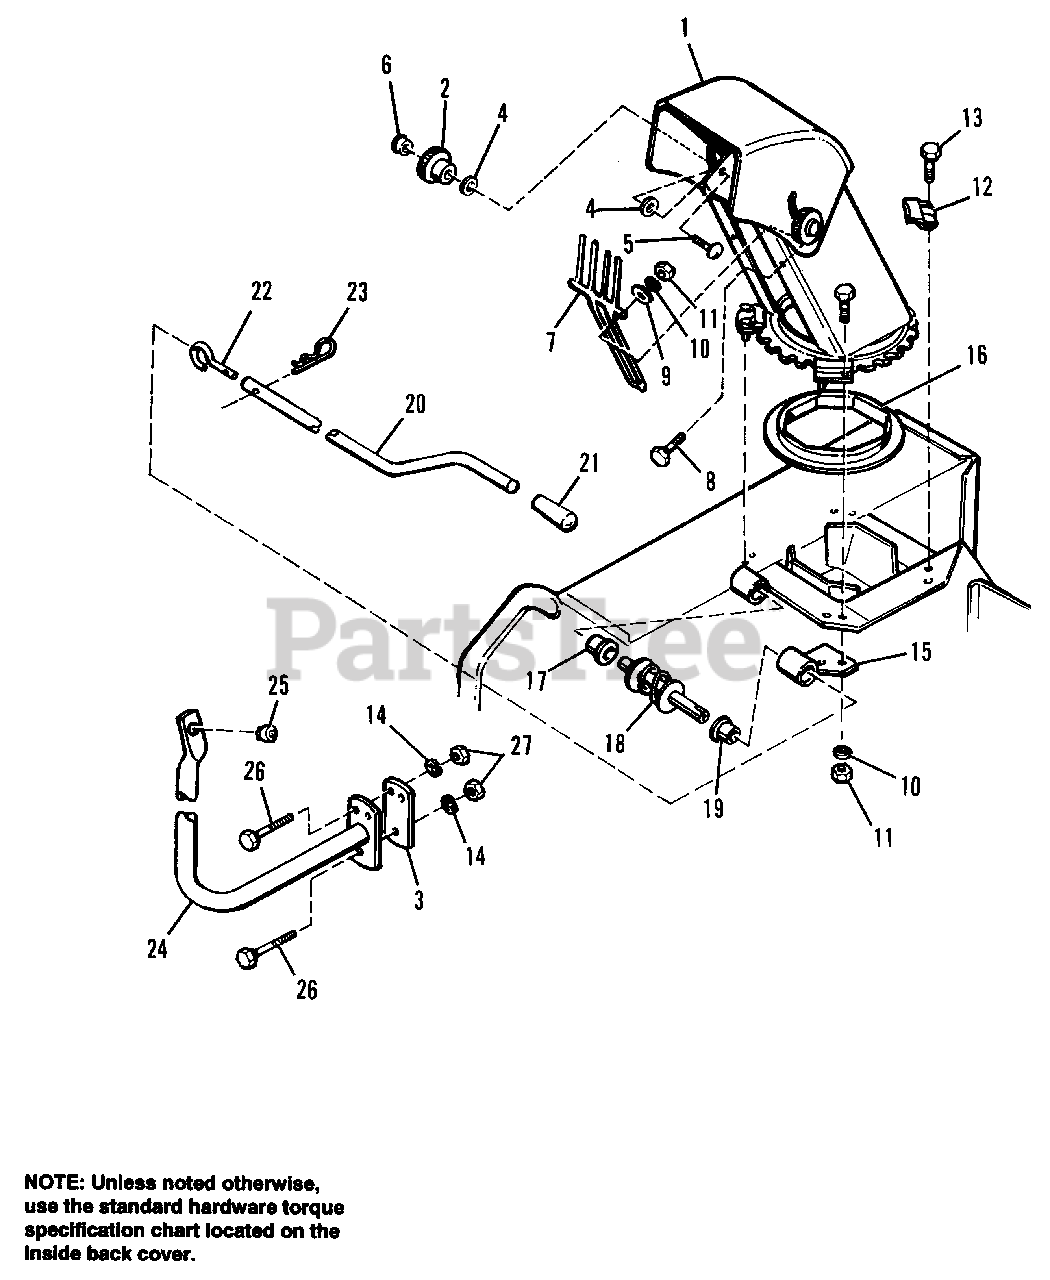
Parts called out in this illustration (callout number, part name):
1	CHUTE & DEFLECTOR ASSY.
3	SUPPORT, Fixation
4	WASHER, Nylon, 13/32 x 1 x 1/16
5	CARRIAGE BOLT, 5/16-18 x 1-1/2
6	NUT, Hex, Lock Esna, 5/16-18
8	CAPSCREW, Hex Hd., 1/4-20 x 3/4
9	WASHER, Plain, 5/16
10	LOCKWASHER, 1/4
11	NUT, Hex, 1/4-20
12	PLATE, Retaining
13	CAPSCREW, Hex Hd., 1/4-20 x 1/2
14	LOCKWASHER, 3/8
15	SUPPORT, Worm
16	RING, Nylon
17	BUSHING, Plastic, 1-5/16
18	WORM, Rotation, Clockwise
19	BUSHING, Plastic, 1-11/16
21	GRIP, Handle
22	HOOK, Handle
23	CLIP, Hairpin, 3/32 x 1-7/8
24	BRACKET, Support, Handle
25	GROMMET, Plastic
26	CAPSCREW, Hex Hd., 3/8-16 x 1-1/4
27	NUT, Hex, 3/8-16
